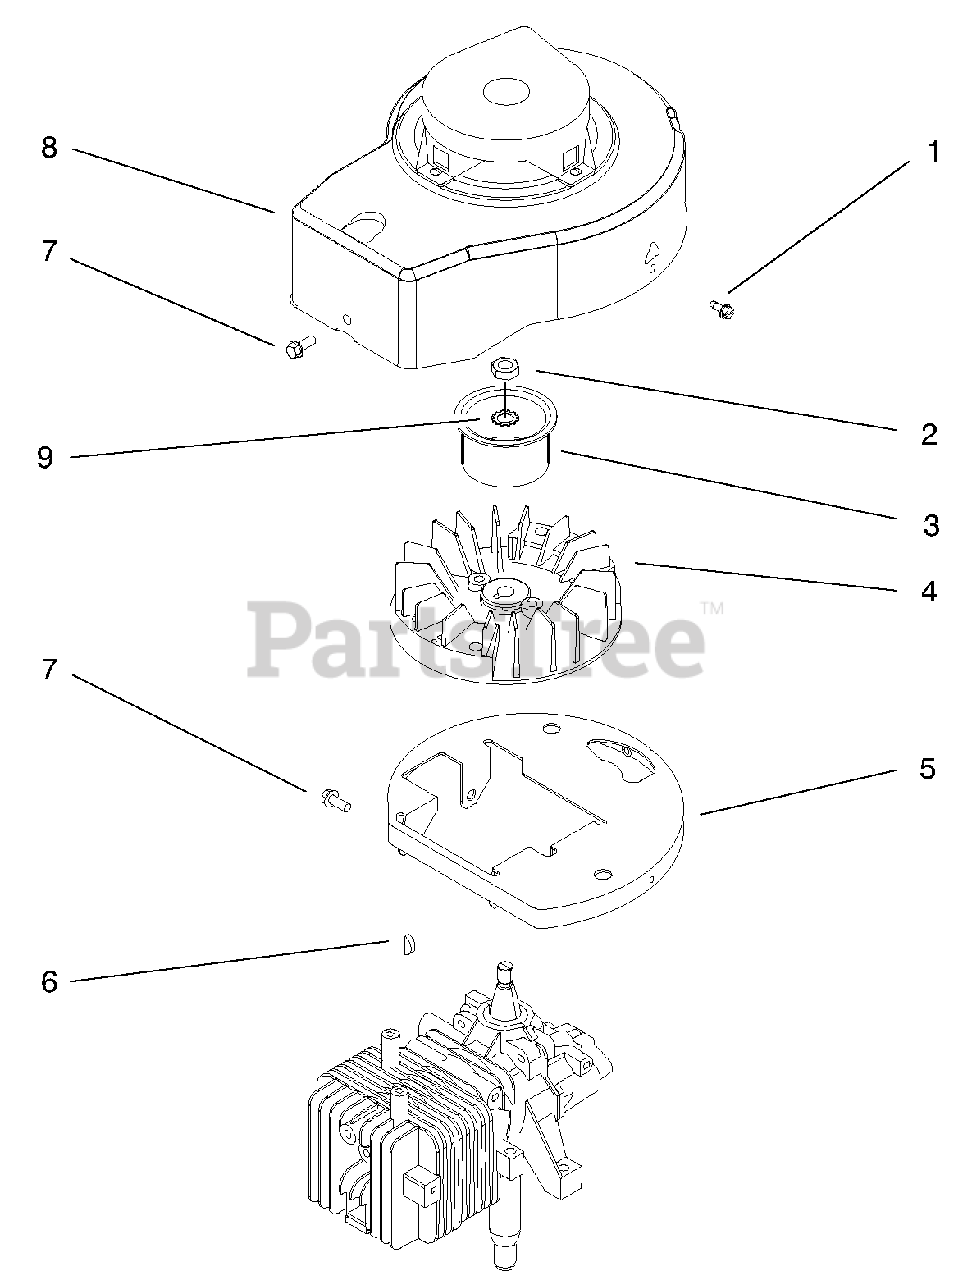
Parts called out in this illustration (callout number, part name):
3	Hub-Starter
4	Flywheel
5	Base-Shroud
7	Screw
8	Shroud Assembly
9	Washer-Lock
